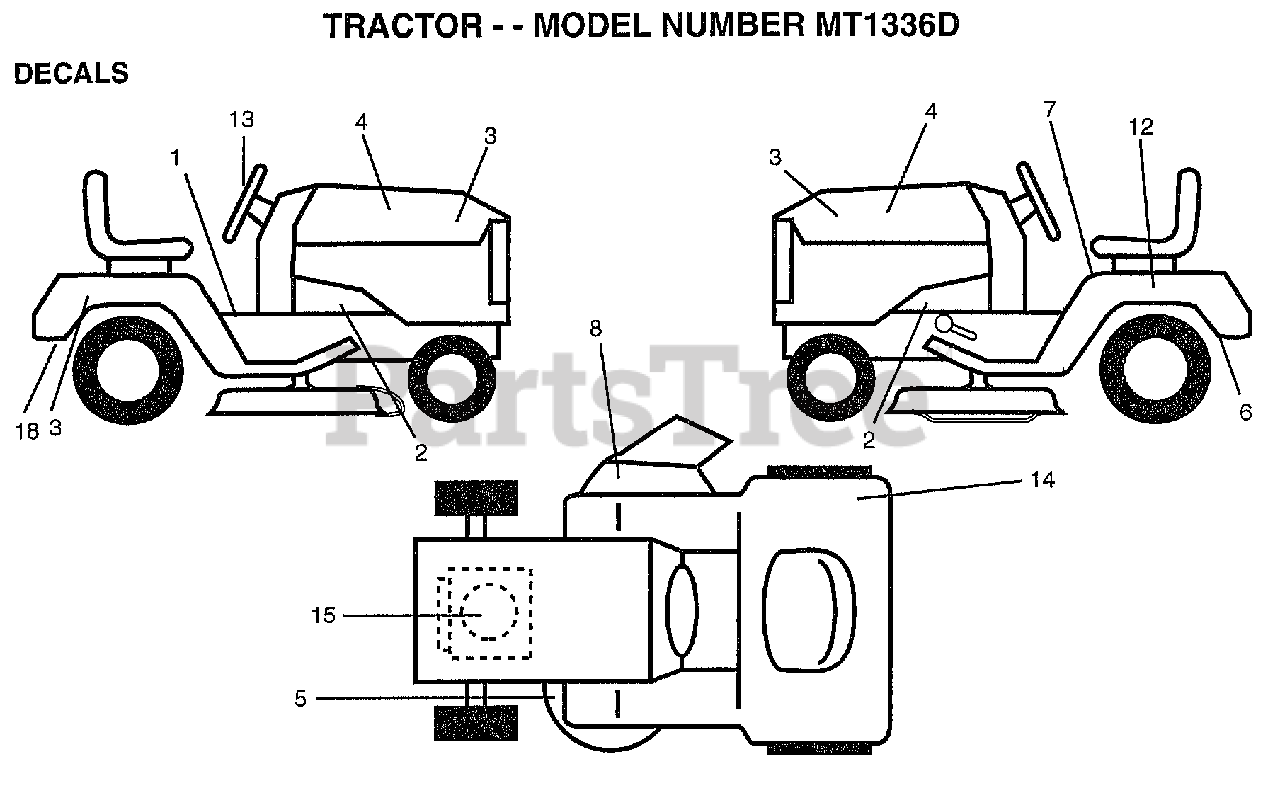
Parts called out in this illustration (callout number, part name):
1	DECAL CLUTCH/BRAK
2	"DECAL CHASSIS,HOT"
3	NAMEPLATE.MOTEC.S
4	"DECAL-HOOD,MTC300"
5	DECAL.V.BELT
6	DECAL.DRAWBAR.LDL
7	DECAL.READ.O.MANU
8	DECAL.DANGER.CUTF
12	DECAL.BATRY.3-3908
13	"DECAL-WHEEL,STEER"
15	DECAL.HP.ENG.B&S13HP
18	DECAL.EURO.ST.CE.
